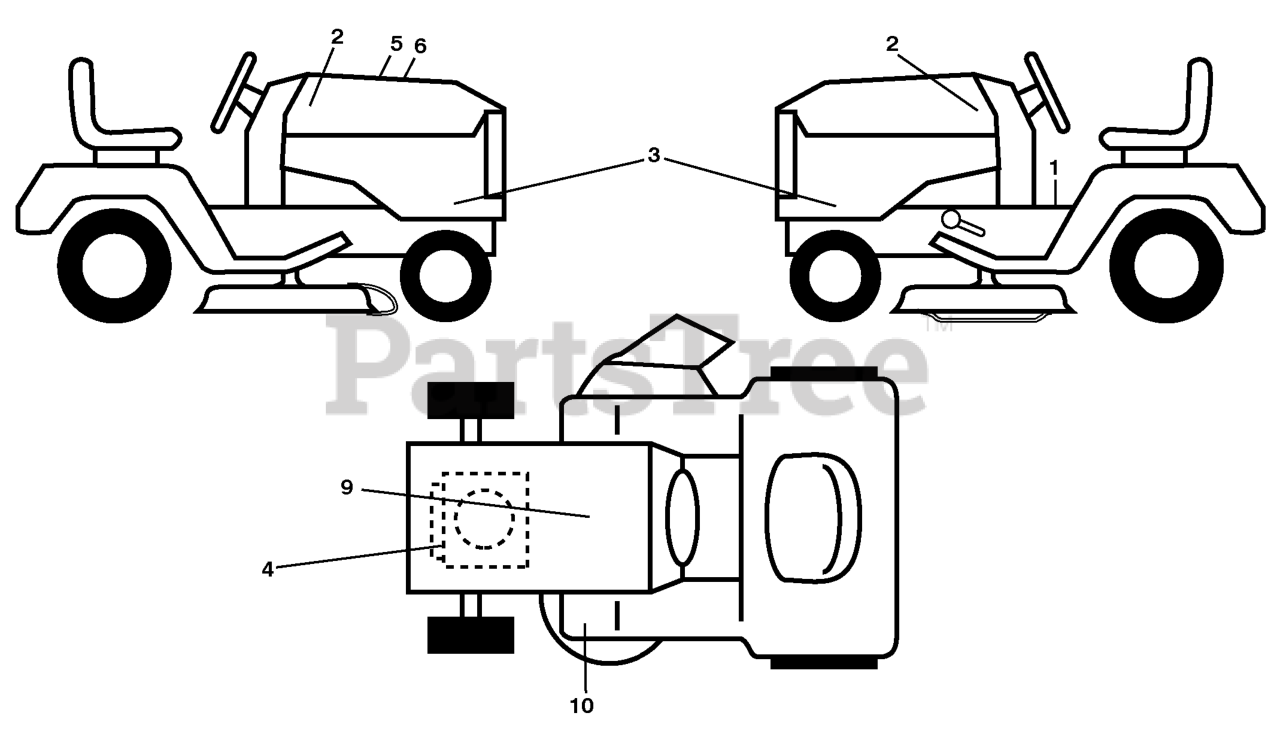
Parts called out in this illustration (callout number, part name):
1	DECAL.FENDER.WARNING.ENG
2	RP.DECAL.BADGE.170MM.TEXTLOGO
3	DECAL.SIDE PANEL YTH22V42LS
4	DECAL, ENG. HP
5	DECAL.WARNING.CUST.RESP.E85.
6	DECAL, REPLACEMENT
9	DECAL BTRY SYMBOLS
10	DECAL.PEDAL.HUSQ.CROWN
